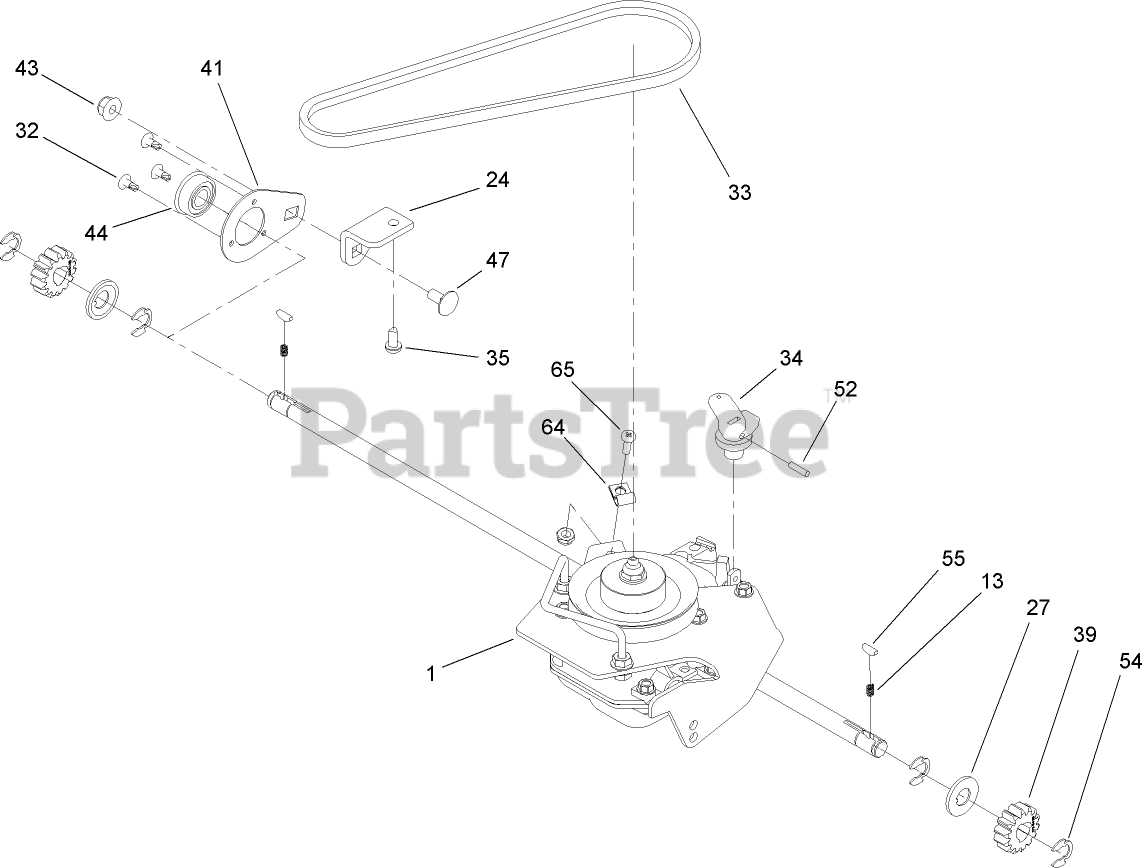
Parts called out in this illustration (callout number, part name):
1	GEAR CASE ASM
13	SPRING-COMPRESSION
24	BRACKET-BEARING
27	WASHER-THRUST, OUTER
32	SCREW-TAP
33	BELT-V, TRACTION
34	LEVER-SHIFT
35	SCREW-TP
39	GEAR-PINION
41	PLATE-BEARING
43	NUT-HF, NI
44	BEARING-BALL
47	SCREW-CARR
52	PIN-COIL
54	RING-RETAINING
64	R-CLAMP
65	SCREW-PPHTF
